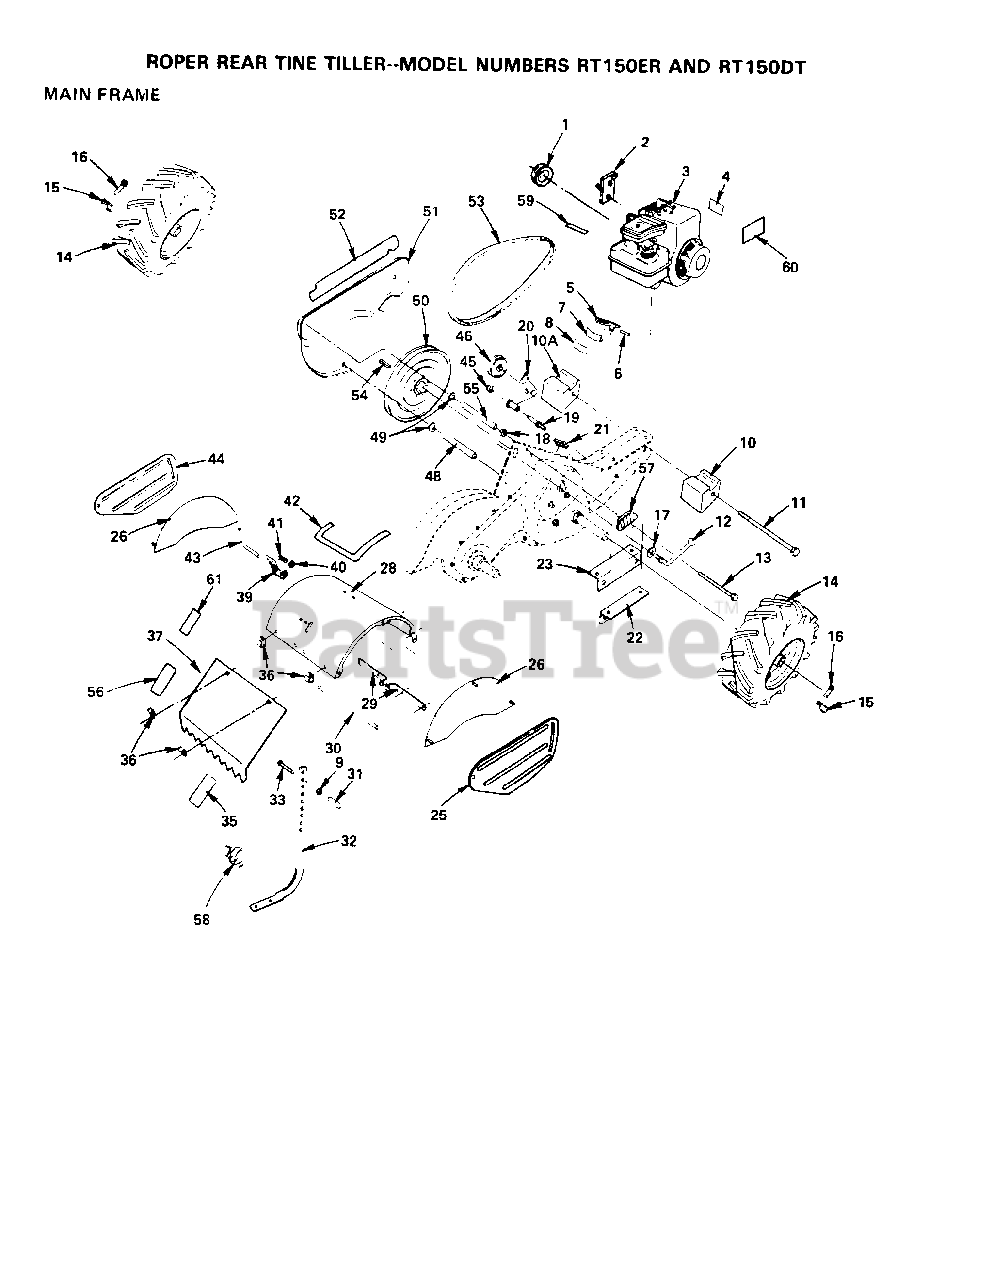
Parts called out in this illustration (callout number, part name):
2	BRACKET ASSY CRT
5	LEVER ASM CRT
7	PANEL TI
8	DECAL CRT
9	NUT.HEX.3/8-16UNC
10	COUNTERWEIGHT CRT
10A	COUNTERWEIGHT CRT
11	BOLT CRT
12	LEVER LOCK CRT
13	BOLT-HEX TI
15	RETAINER M
17	WASHER CRT
18	NUT.HEX.5/16-18
19	SHIFT ARM CRT
21	CONDIUT CLIP T
22	BRACKET RH CRT
23	BRACKET LH CRT
25	SHIELD.SD.OUT.RH
26	SHIELD ASSY - SIDE
31	GRIP CRT
33	BOLT
36	HINGE CRT
37	SHIELD LEVEL CRT
39	LATCH BRACKET TI
40	KLIP RING TI
41	SPRING TI
42	DECAL - TINE SHIELD
43	STAKE PIN TI
45	KLIP RING
46	PULLEY-IDLER TI
49	WASHER
50	"SHEAVE 10"" CRT"
54	KEY T
56	DECAL - DEPTH ADJUSTMENT
57	LOCK CRT
58	SPRING CRT
61	PAD IDLER TI
